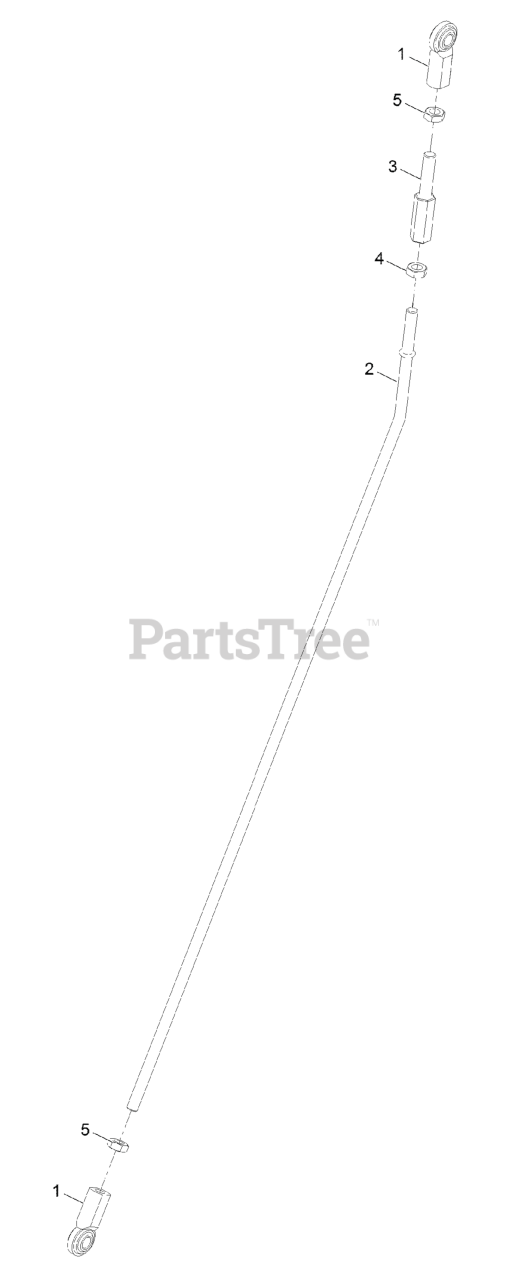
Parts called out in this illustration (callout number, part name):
1	JOINT-BALL, END
2	LINKAGE-MOTION
3	ROD-ADJUSTMENT
4	NUT-HEX JAM, LH
5	NUT-HJ
